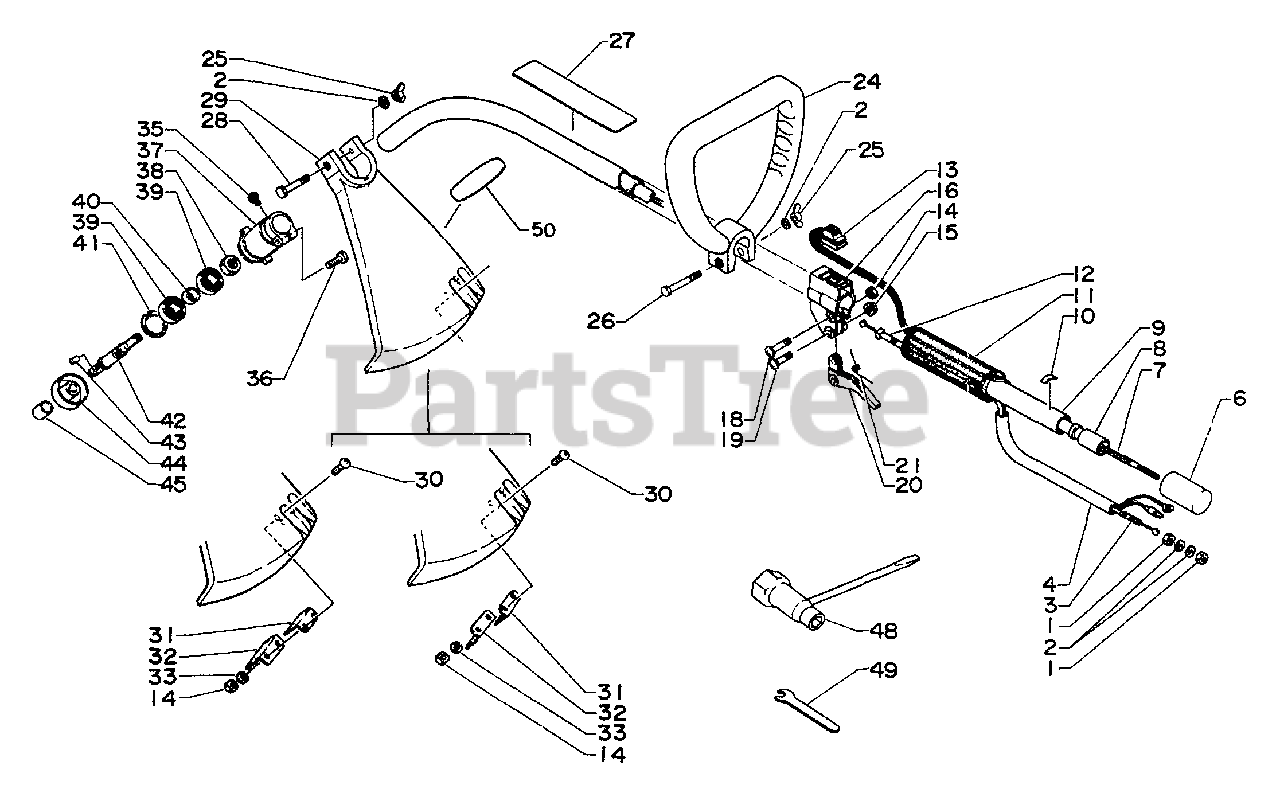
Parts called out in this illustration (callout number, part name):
2	WASHER - 6
3	CABLE, THROTTLE
4	TUBE
6	Cap, housing
7	DRIVESHAFT - FLEXIBLE
8	BUSHING
9	PIPE, MAIN
10	LABEL - ALIGNMENT
11	GRIP, HANDLE
12	GUIDE, CABLE
13	IGNITION SWITCH ASSY
15	LOCKNUT - 5
16	BRACKET, THROTTLE
18	SCREW - 5X28
19	SCREW - 5X30
20	TRIGGER, THROTTLE
21	SPRING, TRIGGER
24	HANDLE ASSY
25	WINGNUT - 6
26	BOLT - 6X40
27	LABEL - CAUTION
27	SHIELD ASSY
28	BOLT - 6X50
29	SHIELD, DEBRIS - PLASTIC
30	SCREW - 5X14
31	KNIFE, TRIMMER LINE
33	LOCKWASHER - 5
35	SCREW - 4X10
36	BOLT - 5X25
37	CASE, GEAR
38	NUT - 12 -- LEFT HAND
39	BEARING, BALL - 6001 DDU
41	RING, RETAINING - 28
42	GEAR - SHAFT
43	PIN - 3X6
44	ADAPTOR, BLADE - UPPER
45	CAP, DRIVESHAFT
48	T-WRENCH - 8X19mm
49	SPANNER - 10mm
50	LABEL - ECHO
